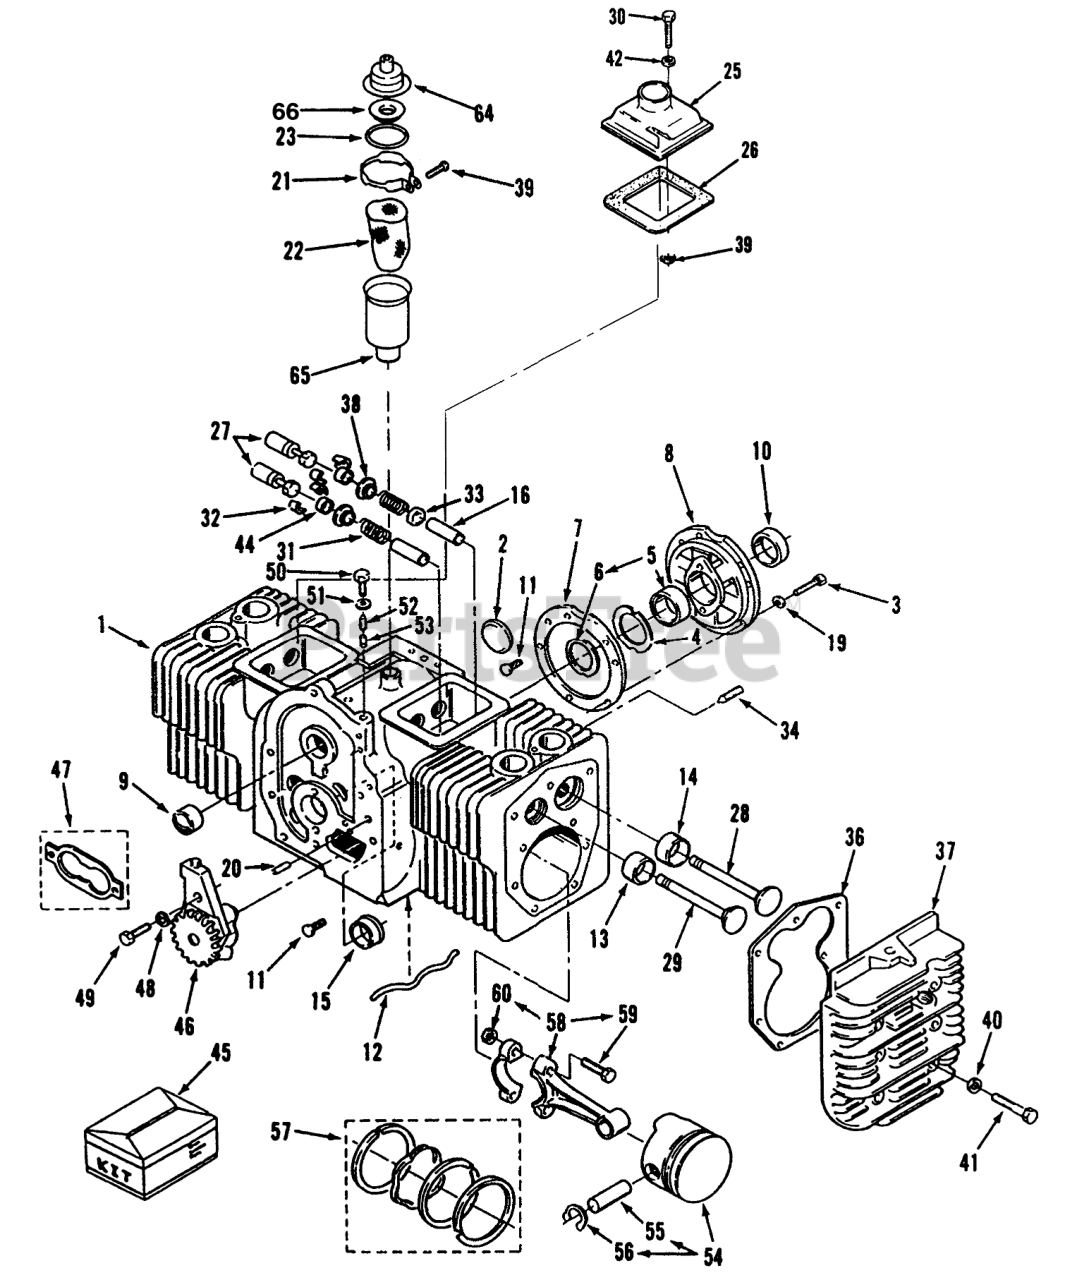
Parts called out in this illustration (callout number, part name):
1	CYLINDER BLOCK
3	HEX HD CAPSCREW
5	BEARING KIT (STANDARD SLEEVE)
6	WASHER
7	Gasket
8	PLATE-BEARING, REAR
9	SLEEVE-BEARING
11	Screw
12	OIL TUBE
13	Standard
14	Standard
15	Standard
16	Guide-ExhaustValve
19	Washer
20	Pin
21	Clamp
22	FILTER
23	SEAL - O-RING
25	VALVE-COVER L.H.
26	GASKET
27	Tappet
28	Intake Valve
29	Intake Valve
30	HHCS 1/4-20 X 1 3/4
31	Spring
32	VALVE SPRING LOCK
33	Seal
34	Screw
36	Gasket
37	Right Side
38	Washer
39	SCREW-TAPPING, ROUND HEAD
40	WASHER
41	Bolt
42	Washer
44	VALVE CAP
45	ENGINE GASKET KIT
46	Oil Pump
47	Oil Pump Gasket Kit
48	WASHER-FLAT
50	SCREW-HH
51	Washer
52	Spring
53	Piunger
54	Standard
55	Pin-Piston
56	Retaining Ring
57	RING/PISTON KIT
58	CONNECTING ROD W/NUT
59	Rod Bolt
60	Nut
64	BREATHER-CAP AND VALVE
65	TUBE-BREATHER
66	SCREEN-BREATHER TUBE
